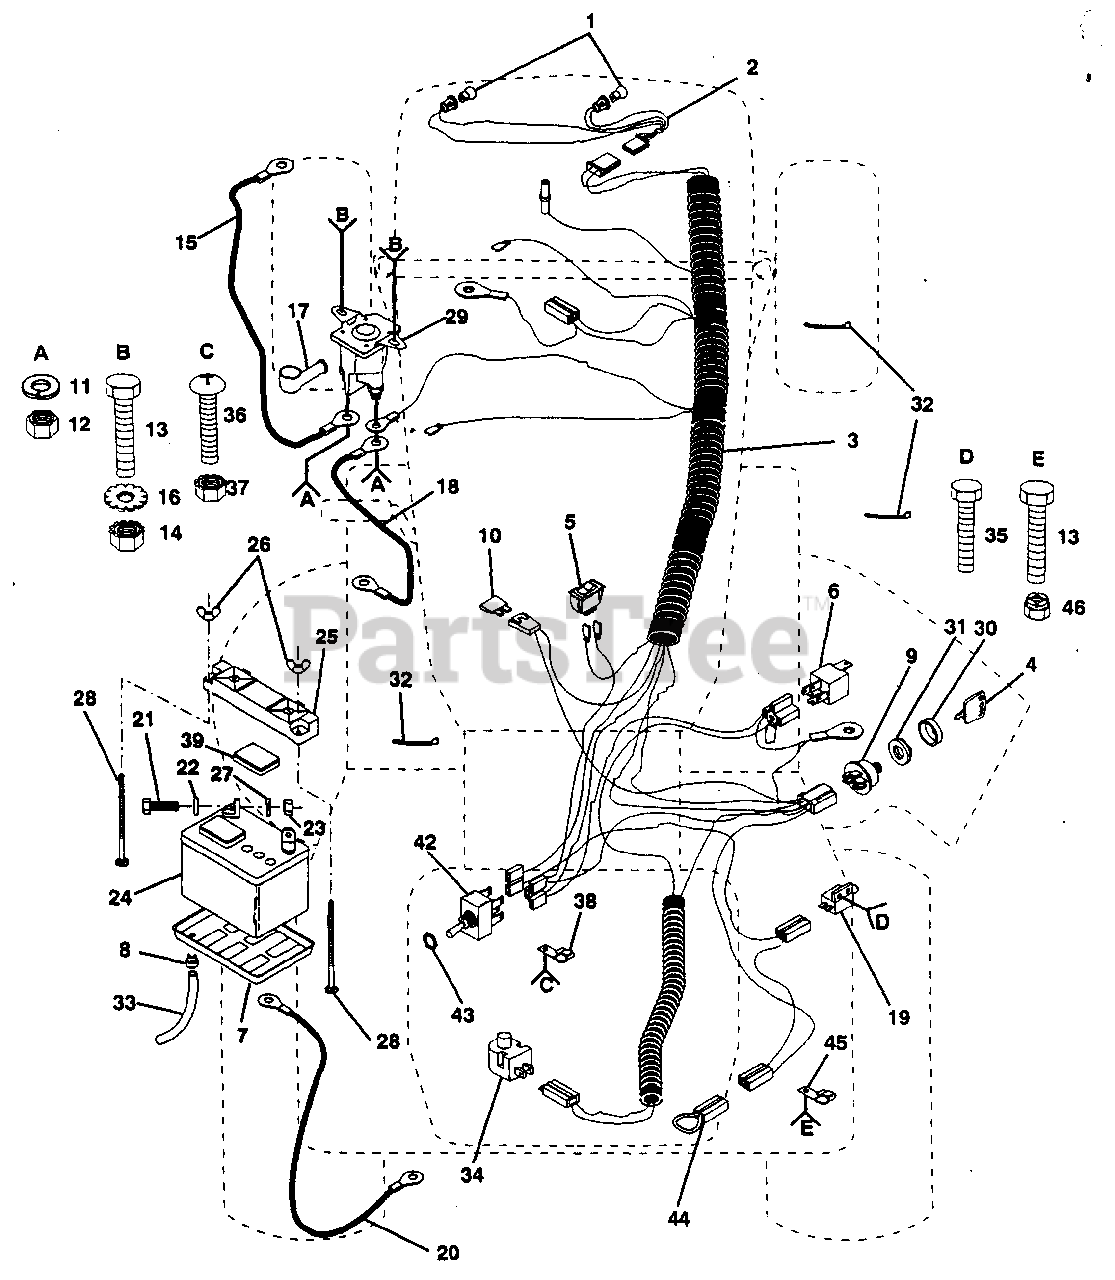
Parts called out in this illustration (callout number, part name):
1	Bulb, Light (AYP part number)
2	Harness, Light Socket (AYP part number)
3	Harness, Ignition (AYP part number)
4	Key, Molded (AYP part number)
5	Switch, Light (AYP part number)
6	Relay (AYP part number)
7	Tray, Battery (AYP part number)
8	Clamp, Hose (AYP part number)
9	Switch, Ignition (AYP part number)
10	Fuse (AYP part number)
11	Washer, Lock 1/4 (AYP part number)
12	Nut, Hex Jam 1/4 20 (AYP part number)
13	Bolt, Hex 1/4-20 x 1/2 Grade 5 (AYP part number)
14	Nut, Keps 1/4-20 (AYP part number)
15	Cable Assembly (AYP part number)
16	Washer, Lock, Ext. Tooth 1/4 (AYP part number)
17	Cover, Terminal (AYP part number)
18	Cable, Battery (AYP part number)
19	Switch, Interlock (AYP part number)
20	Cable, Battery (AYP part number)
21	Bolt, Hex 1/4-20 x 3/4 (AYP part number)
22	Washer 9/32-5/8 x 16 Gauge (AYP part number)
23	Nut, Hex 1/4-20 (AYP part number)
24	Battery (AYP part number)
25	Guard, Terminal (AYP part number)
26	Nut, Wing 1/4-20 (AYP part number)
27	Washer, Lock, Heavy Helical Spring (AYP part number)
28	Bolt, Carriage 1/4-20 x 7-1/2 (AYP part number)
29	Solenoid (AYP part number)
30	Bezel, Ignition (AYP part number)
31	Nut, Ignition (AYP part number)
32	Cable Tie (AYP part number)
33	Tube, Battery Tray (AYP part number)
34	Switch, Seat (AYP part number)
35	Screw, Hex Tapping #10-24 UNC x 1/2 (AYP part number)
36	Screw, Slotted Pan Head #10-32 x 1/2 (AYP part number)
37	Nut, Keps #10-32 x 1/2 (AYP part number)
38	Clip, Insulated (AYP part number)
39	Caps, Battery (AYP part number)
42	Switch P.T.O. (AYP part number)
43	Nut, Hex (AYP part number)
44	Loop, Wire (AYP part number)
45	Clip, Insulated (AYP part number)
46	Nut, Crownlock 1/4-20 (AYP part number)
